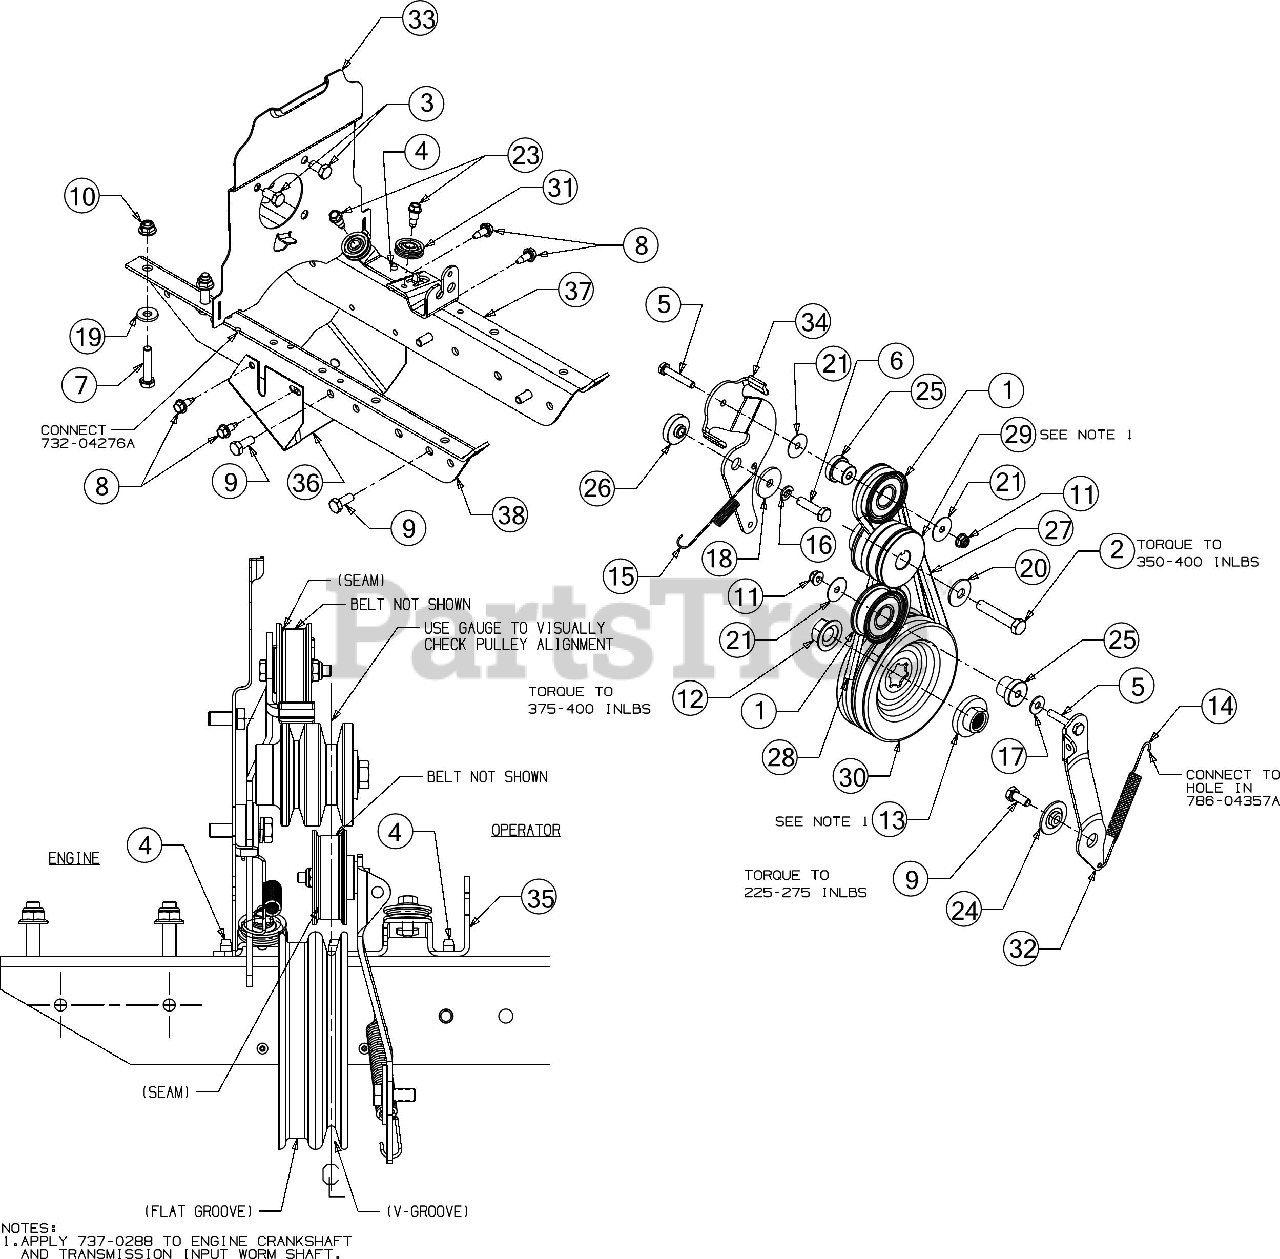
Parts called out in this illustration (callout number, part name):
1	IDLER PULLEY ASSEMBLY
1	BALL BEARING
2	HEX SCREW 3/8-24 X2.00
3	HEX SCREW 5/16-24 x .62
4	SCREW 1/4-20 X.500
5	SCREW 1/4-20 x 1.50 GR.5
6	SCREW 5/16-24 x 1.25 GR5
7	SCREW 5/16-18 x 1.5 LG
8	SCREW 1/4-14 x .625
9	SCREW 5/16-18 x .750
10	FLANGE LOCK NUT 5/16-18
11	FLANGE LOCK NUT
12	FLANGE NUT W/HUB
13	PULLEY HUB
14	RETURN SPRING
15	EXTENSION SPRING
16	LOCK WASHER 5/16
17	FLAT WASHER .28 ID x .74 OD x .063
18	WASHER-5/16 x 1.25X 1.27
19	BELLVILLE WASHER .827 x .331 x .098
20	BELL WASHER
21	FLAT WASHER
22	GREASE (NOT SERVICEABLE)
23	SHOULDER SCREW
24	PIVOT IDLER SPACER
25	SHOULDER SPACER
26	PIVOT IDLER SPACER
27	V-BELT FWD DRIVE 4L x 25.375
28	V-BELT REV DRIVE 3L x 29.125
29	ENGINE PULLEY
30	TRANSMISSION PULLEY
31	CABLE GUIDE ROLLER
32	FORWARD IDLER BRACKET
33	REVERSE IDLER BRACKET
34	REVERSE IDLER BRACKET
35	CABLE BRACKET ROLLER
36	PULLEY SHIELD
37	FRAME-MOUNT (RH)
38	FRAME-MOUNT (LH)
